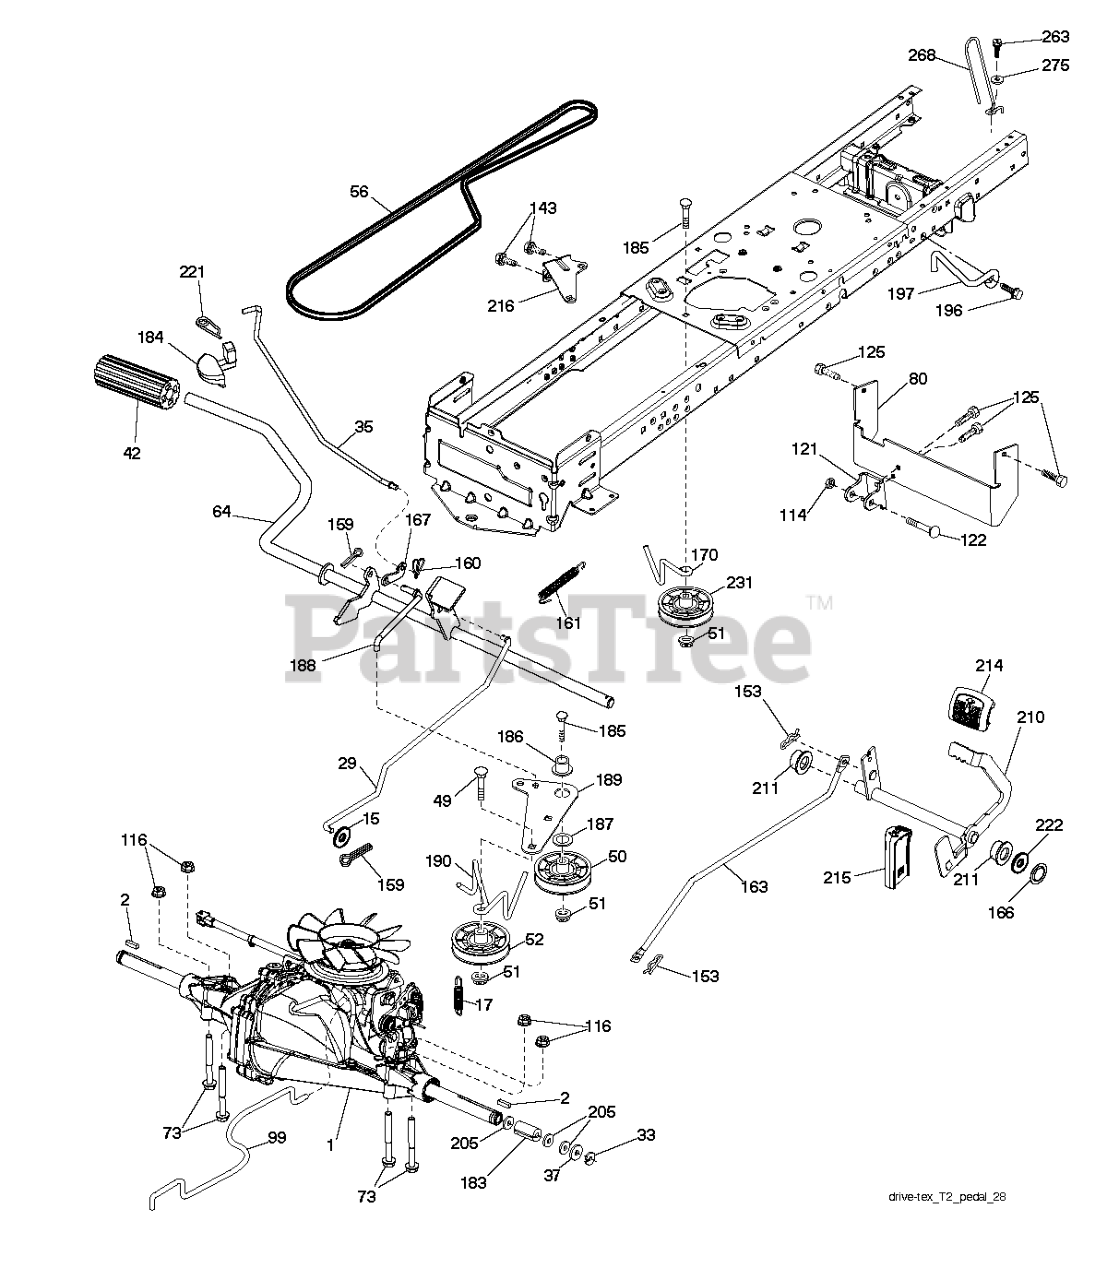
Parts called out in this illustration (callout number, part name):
2	SQUARE KEY
15	WASHER
17	SPRING.BRAKE.HG3000/3500
29	ROD.BRAKE.T2.TEX
35	ROD.CNTRL.PARK.PREDATOR.LT.TEX
42	PEDAL COVER T
50	IDLER.FLAT.910.OFFSET
51	NUT LOCK FLG 3/8-16 UNC
52	IDLER.V-GROOVE.910.OFFSET
64	SHAFT.ASM.PEDAL.BRK.CNTR
73	BOLT HEX 5/16-18 GR 5
80	RP.STRAP.TORQUE.FS.T2
99	ROD.ASM.BYPASS.SPRING.T2.FS
114	NUT.71038.31-18.HEX.NYLOCK
116	NUT LOCK HEX FLANGE 5/16-18
121	BRACKET STRAP TORQUE
122	BOLT.5/16-18X2.5
125	SCREW
143	Screw 5/16-18 x 1/2 Hex, Self Tapping 5/16-18 x 1/2
153	RETAINER M
159	COTTER PIN
160	RETAINER CLIP
161	SPRING, RETURN LT
163	ROD.CONTROL.PCH.T2.TEX
166	NUT.PUSH.625
167	LATCH.BRAKE.SPRING
170	KEEPER.CENTER SPAN.1.688
183	SPACER, AXLE PVST
184	HANDLE PARKING BRAKE
186	SPACER.RETAINER
187	WASHER 12/32X2X10GA
188	RP.LINK.CLUTCH.GROUND.DRIVE
189	BELLCRANK.GROUND.DRIVE.TEX.
190	KEEPER.BELLCRANK.DRIVE
196	SCREW 3/8-16X1
197	LINK.CLUTCH.ANIT-ROTAT
210	ROCKER.ASM.PEDAL.CONTR
211	BEARING.NYLON
214	PEDAL.FORWARD.PAD.TEX
215	PEDAL RUBBER REVERSE
216	BRACKET.PULLEY.IDLER.W/TEX
221	RETAINER.SPRING.CLIP.H
222	WASHER 21/32 X 1-1/4 X 10 GA.
231	IDLER.V-GROOVE.1.688.OFFSET
263	SCREW, 3/8-16X3/4
268	WASHER
275	GUARD MUFFLER
